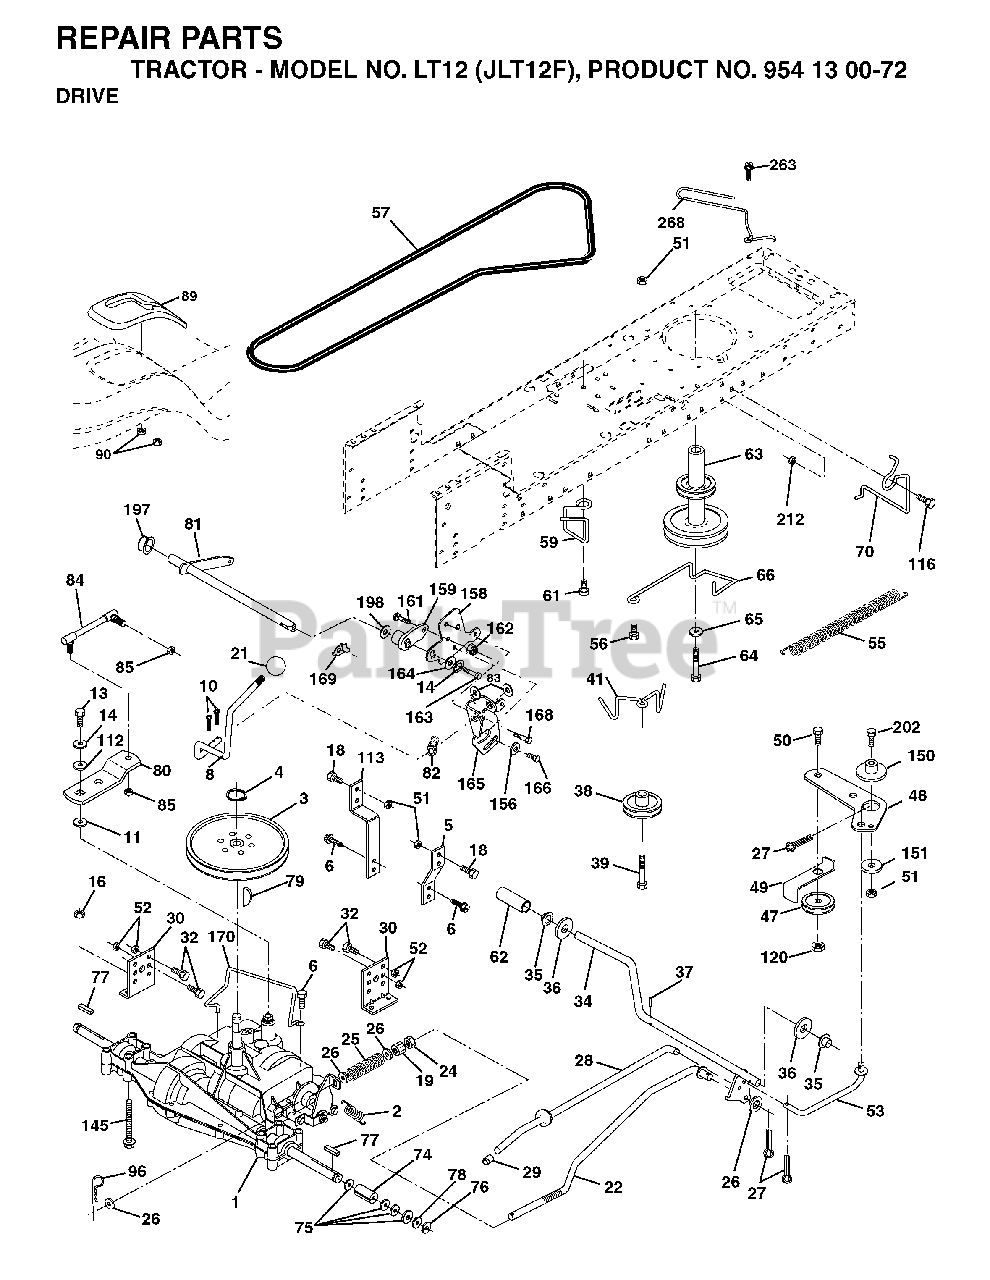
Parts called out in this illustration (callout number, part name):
2	SPRING,BRAKE RETURN
3	PULLEY TRANS
4	RETAINING RING LT
5	STRAP TORQUE
6	SCREW 5/16"
8	ROD SHIFT FENDER ADJUST STLT
10	PIN COTTER
11	WASH-SHFT PLT LT
13	BOLT 1/4-28X3/4
14	LOCKWASHER
16	NUT.71038.31-18.HEX.NYLOCK
19	NUT
21	KNOB.DUCKHEAD.1/2
22	ROD BRAKE
24	NUT
25	SPRING ROD LT
27	COTTER PIN
28	ROD, PARKING BRAKE
29	PLUNGER CAP
30	BRKT, MOUNT TRNSAXLE
32	BOLT
34	SHAFT, FOOT PEDAL
35	BEARING.NYLON
36	WASHER LT
37	DRIVE PIN
38	PULLEY IDLER COMPOSITE
39	BOLT
41	KEEPER, BELT IDLER
47	IDLER PULLEY
48	BELLCRANK, CLUTCH
49	RETAIN BELT
50	BOLT.3/8-16X1.50
51	LOCKNUT
52	LOCKNUT
53	LINK, CLUTCH LT
55	SPRING, RETURN LT
57	V-BELT
59	KEEPER, BELT CENTER
61	SCREW 3/8-16X.875
62	PEDAL COVER T
64	BOLT
65	LOCKWASHER
66	KEEPER BELT ENGINE
74	SPACER AXLE
76	E-RING LT
77	SQUARE KEY
80	ARM SHIFT
82	SHIFT SPRING
83	WASHER
85	NUT LOCK CENTER 1/4 -28 FNTHD
96	RETAINER M
112	WASHER LT
113	STRAP TORQUE LH LT
116	BOLT D
120	NUT LOCK FLG 3/8-16 UNC
150	SPACER, RETAINER
151	WASHER 12/32X2X10GA
156	WASHER.SRRTD.5/16
158	BRACKET
159	HUB
161	BOLT
162	NUT.CROWNLOCK.1/4
165	RP BRACKET
168	BOLT.SHOULDER.5/16-18X
169	PLATE.FASTENING.CROSS.SHAFT
170	KEEPER BELT T/A
197	NYLINER SNAP 5/8" ID
198	WASHER.NYL.7/8IDX.105"HYD CR
202	BOLT
212	NUT
263	SCREW, 3/8-16X3/4
